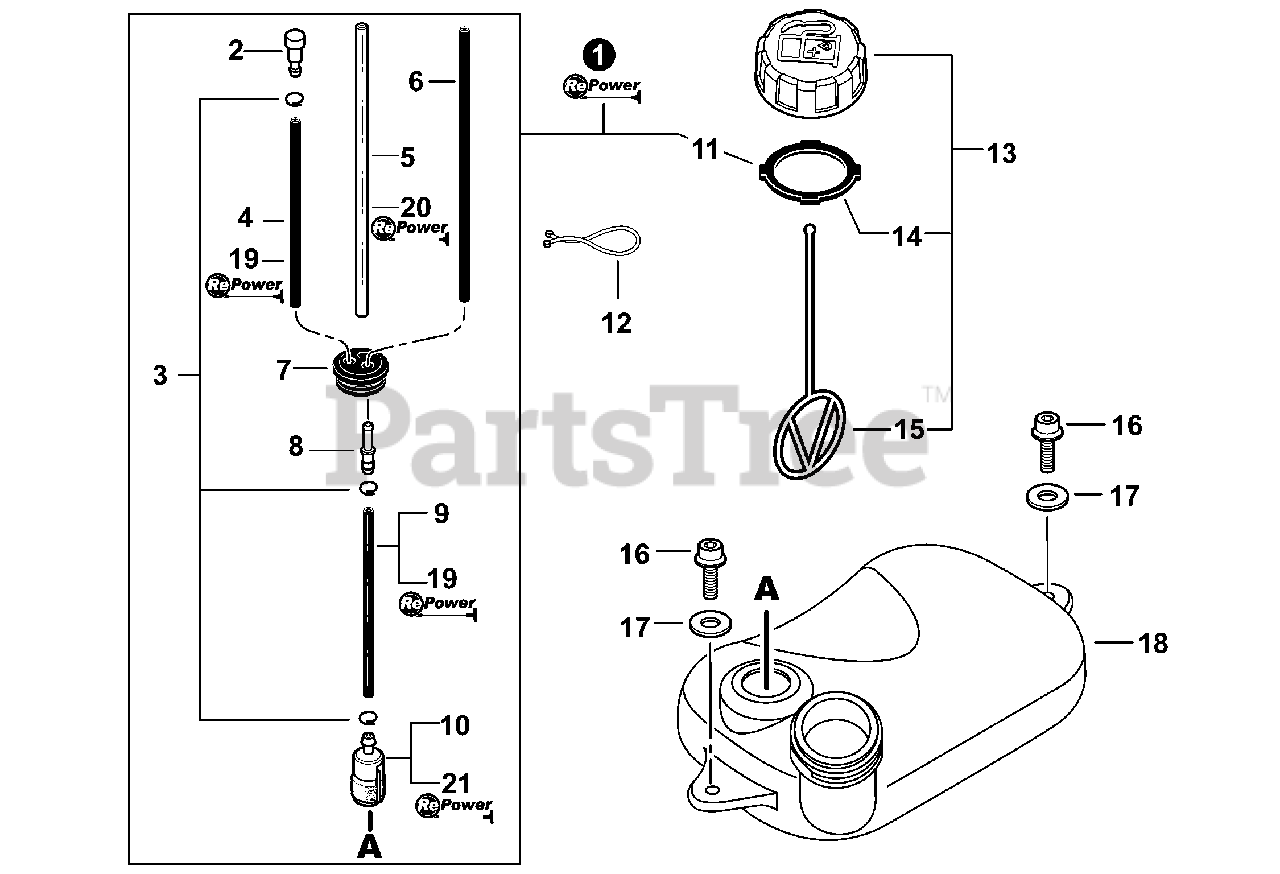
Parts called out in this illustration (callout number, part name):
1	FUEL SYSTEM KIT - REPOWER
2	VENT ASSY
4	PIPE, FUEL 3×5×70 BLACK
5	PIPE, FUEL 3×6×125
6	PIPE, FUEL - 3×5×120 - BLACK
7	GROMMET, FUEL
8	CONNECTOR, PIPE 5×3.5
9	PIPE, FUEL 3×5×90 BLACK
10	FILTER, FUEL
11	GASKET, FUEL CAP
12	CLIP, TUBE
13	CAP ASSY, FUEL
14	GASKET, FUEL CAP
15	CONNECTOR, CAP L= 100mm
16	BOLT 5×20
17	WASHER 5.5×16×2T
18	TANK, FUEL
19	PIPE, FUEL - REPOWER BULK 3×5mm BLACK
20	PIPE, FUEL - REPOWER BULK 3×6mm CLEAR
21	TUNE-UP KIT - REPOWER
